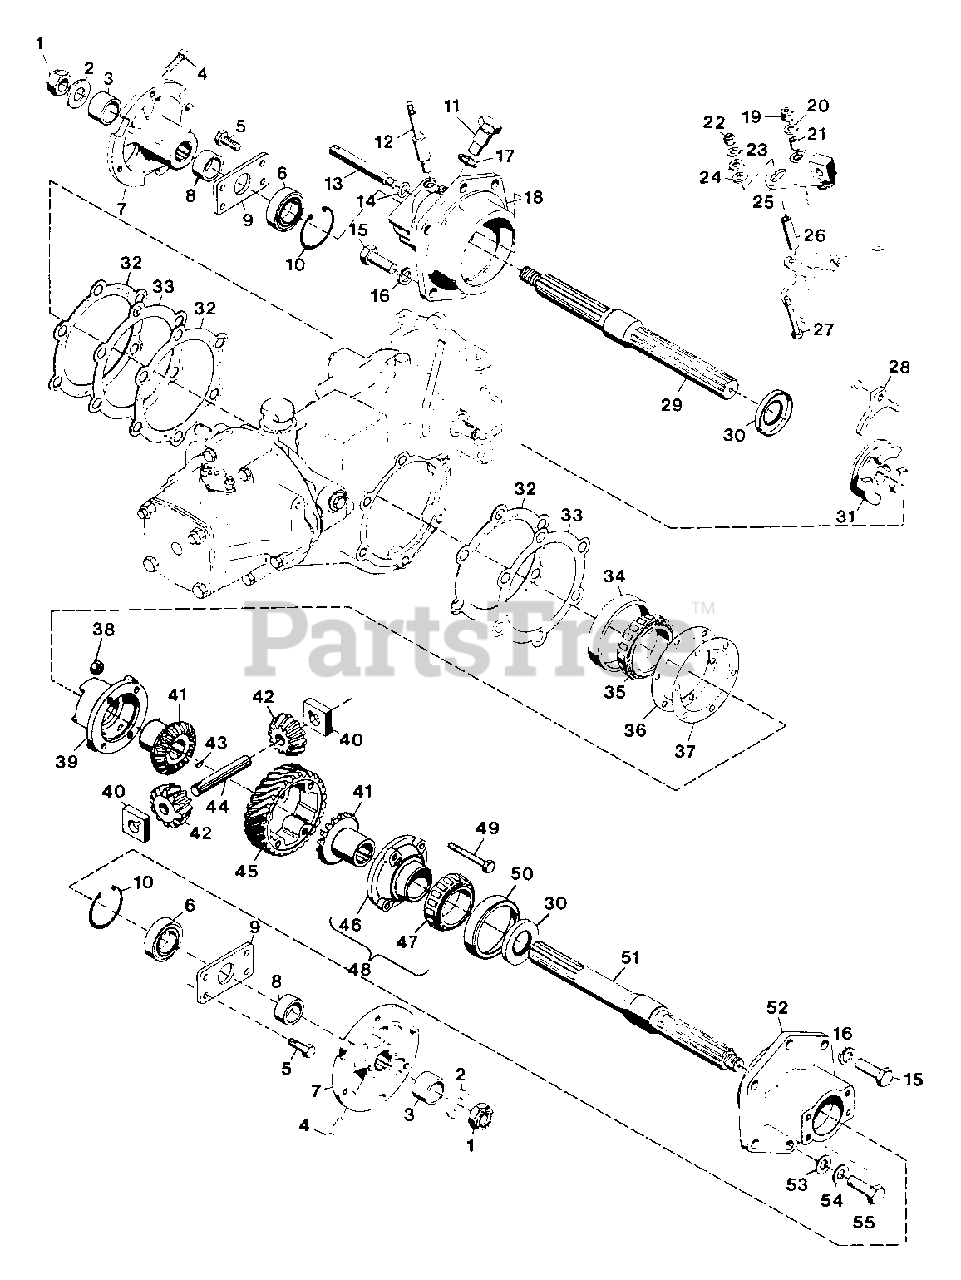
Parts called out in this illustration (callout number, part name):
1	Nut, Hex 3/4-10 Light Thin
2	Washer, Flat .812x1.469x.134
3	Spacer
4	Screw, Set 7/16-14x1.00 SQHCP
5	Bolt, Hex 3/8-16x.750
6	Bearing, Ball 1.000x2.000x.562
7	Hub, Wheel
8	Spacer
9	Plate, End
10	Ring, Retaining 2.000 Bore
11	Bolt, Stationary Clutch
12	Pivot, Stationary
13	Pin, Clutch Sliding
14	O-Ring, .438x.625x.094
15	Bolt, Hex 1/2-13x1
16	Washer, Lock 1/2 Reg.
17	Washer, Oil Strainer Nut
18	Housing, Axle 2-Speed
19	Nut, Lock 5/16-18
20	Washer, Flat .344x.688x.065
21	Bushing, Nylon .375x.503x.875
22	Nut, Lock 1/4-20
23	Washer, Flat .281x.625x.065
24	Washer, Flat .406x.812x.065
25	Weldment, Arm Shifter
26	Bushing
27	Bolt, 1/4-20x2.25 Gr. 8 PHD
28	Yoke, Shifting
29	Axle, Straight Differential Lock
30	Seal, Oil 1.188x2.000x.250
31	Clutch, Sliding Differential Lock
32	Gasket, Axle Housing
33	Shim, Axle Housing .005
34	Cup, Roller Bearing
35	Cone, Roller Bearing
36	Shim, Clutch Worm Gear .020
37	Shim, Clutch Worm Gear .005
38	Nut, Lock 5/16-24
39	Housing, Differential Lock
40	Block, Drive
41	Gear, Differential Bevel
42	Gear, Spider Bevel
43	Key, Woodruff .125x.375 Hard
44	Pin, Spider Pinion
45	Gear, 6 Lead Worm
46	Housing, Differential
47	Cone, Roller Bearing
48	Assembly, Differential Housing
49	Bolt, Hex 5/16-24x3.00
50	Cup, Roller Bearing
51	Axle, Straight
52	Housing, Axle
53	Seal, Oil Drain
54	Washer, Flat .531 x1.062x.095
55	Bolt, Hex 1/2-13x1 Nylon Insert
NS	Decal, Differential Lock French
